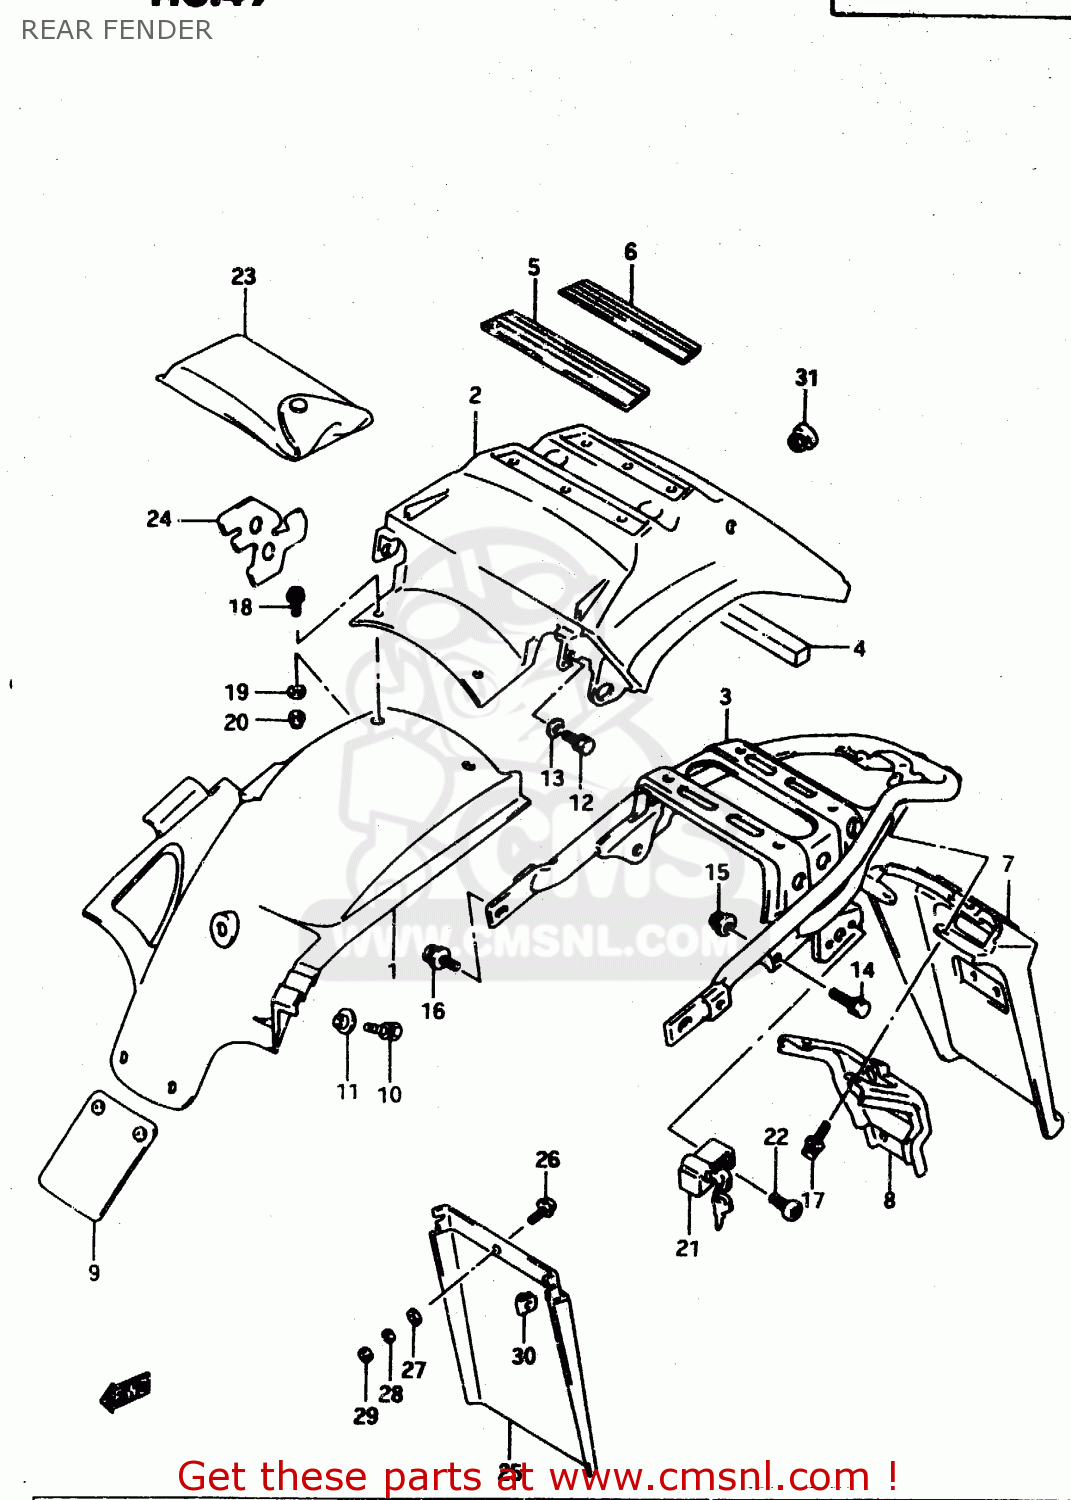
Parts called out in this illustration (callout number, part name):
1	BODY,REAR FENDER,FRONT
2	BODY,REAR FEND
3	REINF,RR FENDER
4	CUSHION,REAR FENDER &
5	CUSHION,REAR FENDER,REAR
6	CUSHION,REAR FENDER,REAR
7	EXTENSION,RR FENDER
8	REINFORCEMENT,RR FENDER EXT
9	GUARD,RR FENDER FR MUD
10	BOLT
11	WASHER
12	BOLT
13	WASHER
14	BOLT
15	NUT
16	BOLT
17	BOLT(6X20)
18	SCREW (M5X16)
19	WASHER (5.5X16X1.2)
20	NUT
21	LOCK SET,HELMET
22	SCREW(6X14)
23	TOOL ASSY
24	SHIELD,REAR FENDER,REAR
25	MUDGUARD,RR FENDER RR
26	SCREW
27	WASHER(5.5X16X1.2)
28	LOCK,WASHER
29	NUT
30	NUT
31	CAP(OD:20)
